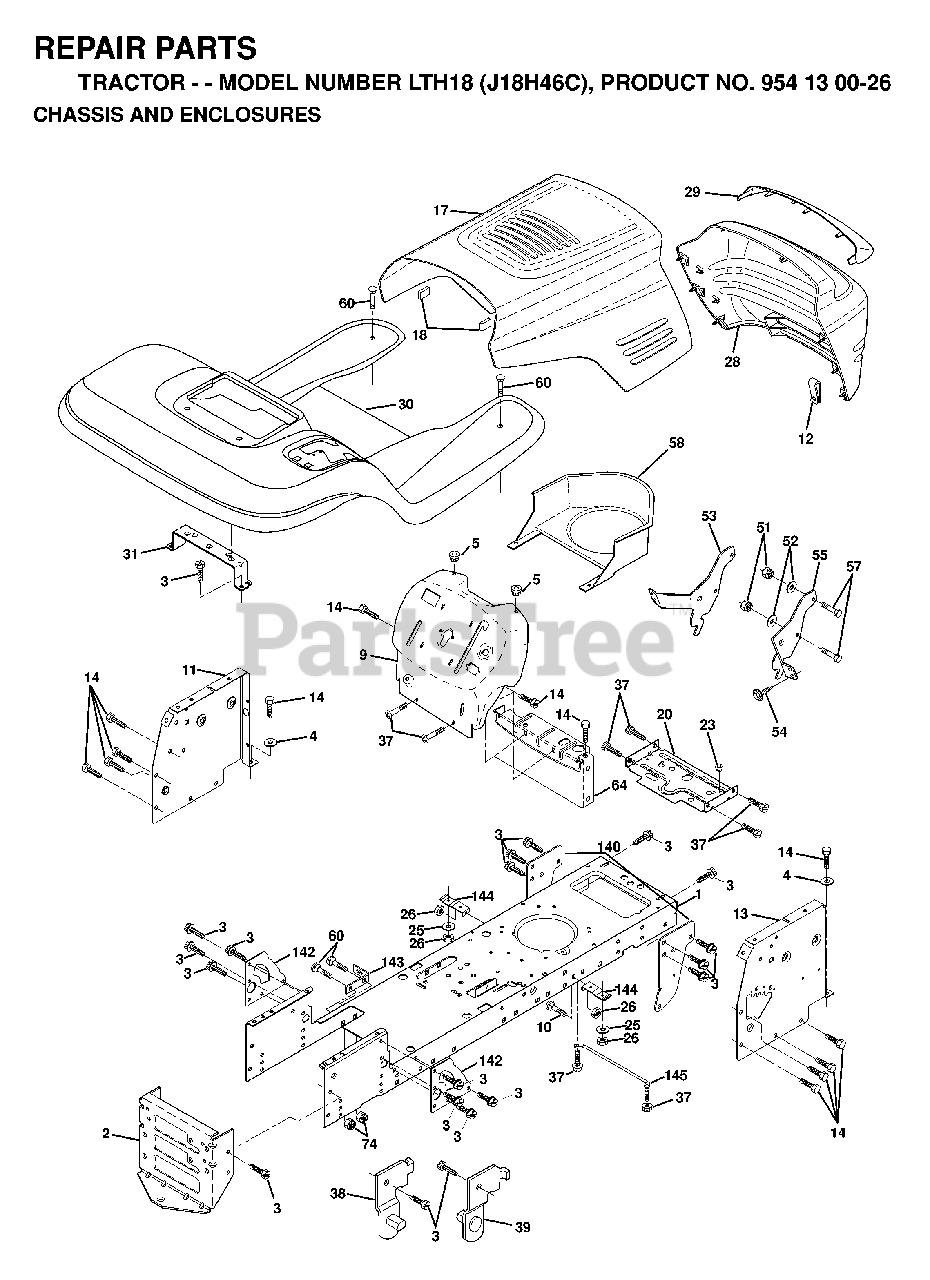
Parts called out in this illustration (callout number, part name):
2	STRETCH DRAWBAR
3	SCREW
5	BUMPER.RUBBER.HOOD
10	BOLT D
11	PANEL DASH LH
13	DASH PANEL
18	BUMPER HOOD T
20	PLATE MTG
23	GROMMET T
25	WASHER
26	NUT
38	BRACKET LH PIVOT
39	BRACKET RH PIVOT
51	LOCKNUT
57	BOLT
58	AIR CONDUCTOR
64	DASH LOWER
74	LOCKNUT
140	BRACKET SUSPENSION FRONT
142	PLATE
143	BRACKET, SWAY BAR
144	BRACKET FOOTREST
145	ROD PIVOT CHASSIS/HOOD
